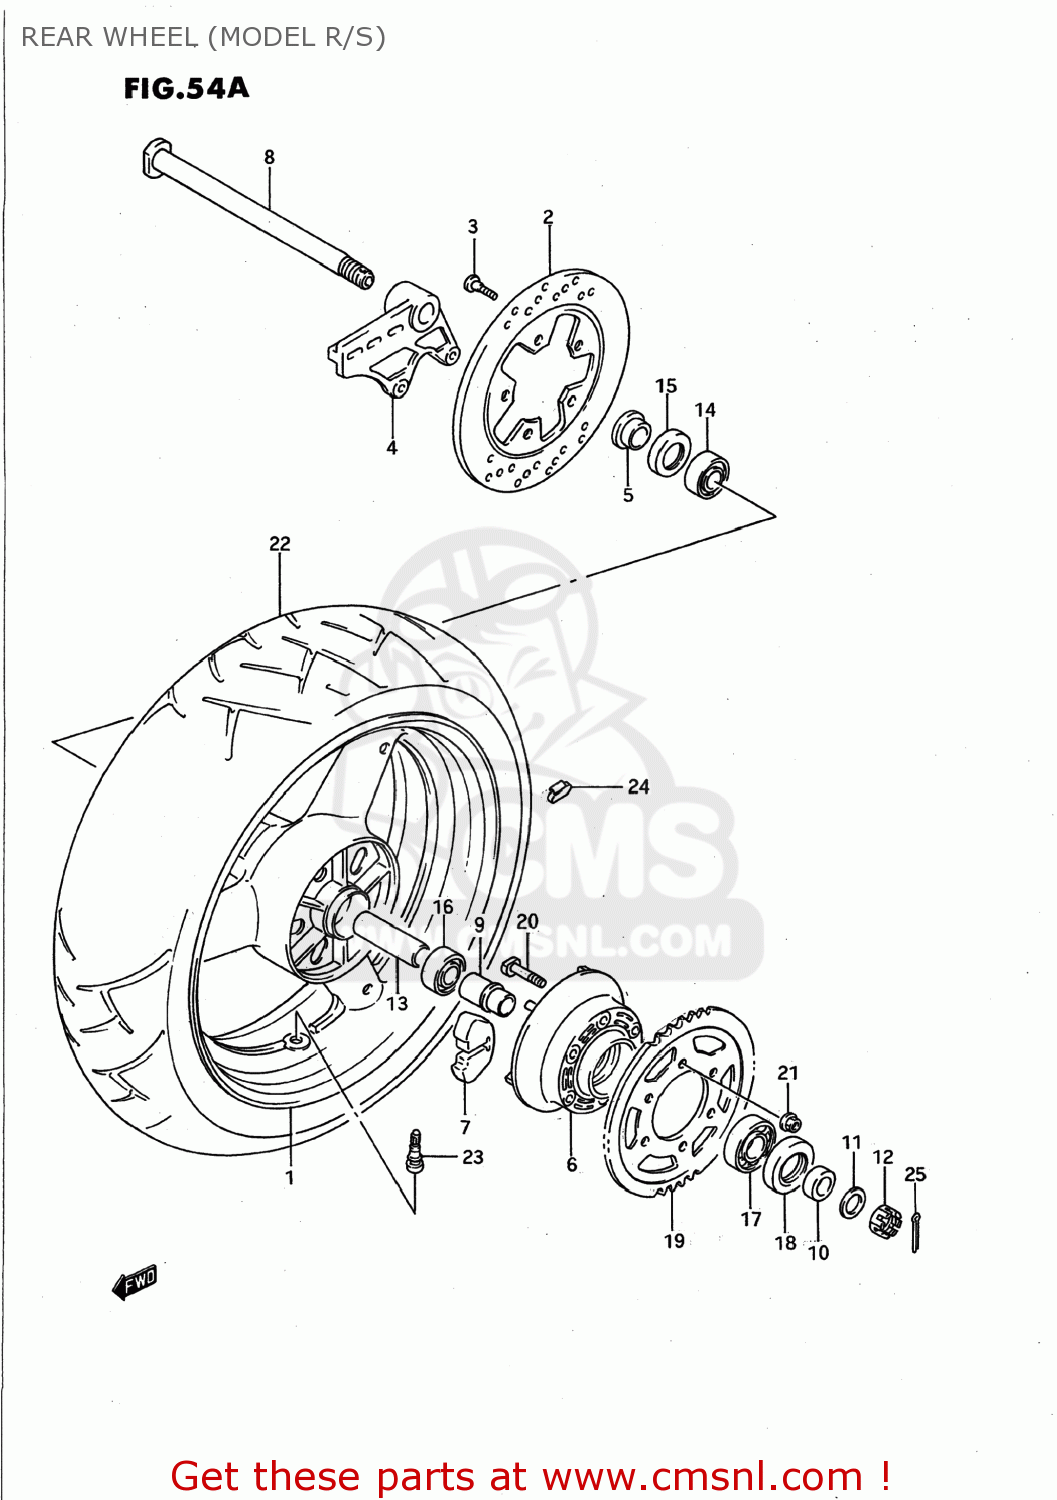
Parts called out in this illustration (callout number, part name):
1	WHEEL,REAR
2	DISC,RR BRAKE
3	BOLT 8X33
4	BRACKET,RR CALIPER
5	SPACER,RR AXLE,R
6	DRUM,RR SPROCKET
7	ABSORBER,RR HUB SHOCK
8	AXLE,RR
9	RETAINER,RR HUB BEARING
10	SPACER,RR AXLE,L
11	WASHER (18.2X28X2.6)
12	NUT
13	SPACER,RR WHEEL HUB BEARING
14	BEARING(20X47X14)
15	SEAL,OIL(28X47X7)
16	BEARING(20X47X14)
17	BEARING(25X62X17)
18	SEAL,OIL(35X62X8)
19	SPROCKET,RR(NT:42)
20	BOLT
21	NUT
22	TIRE,REAR 180/55 ZR17
23	VALVE ASSEMBLY,WHEEL,TR412
24	BALANCER,WHEEL
25	PIN, COTTER
